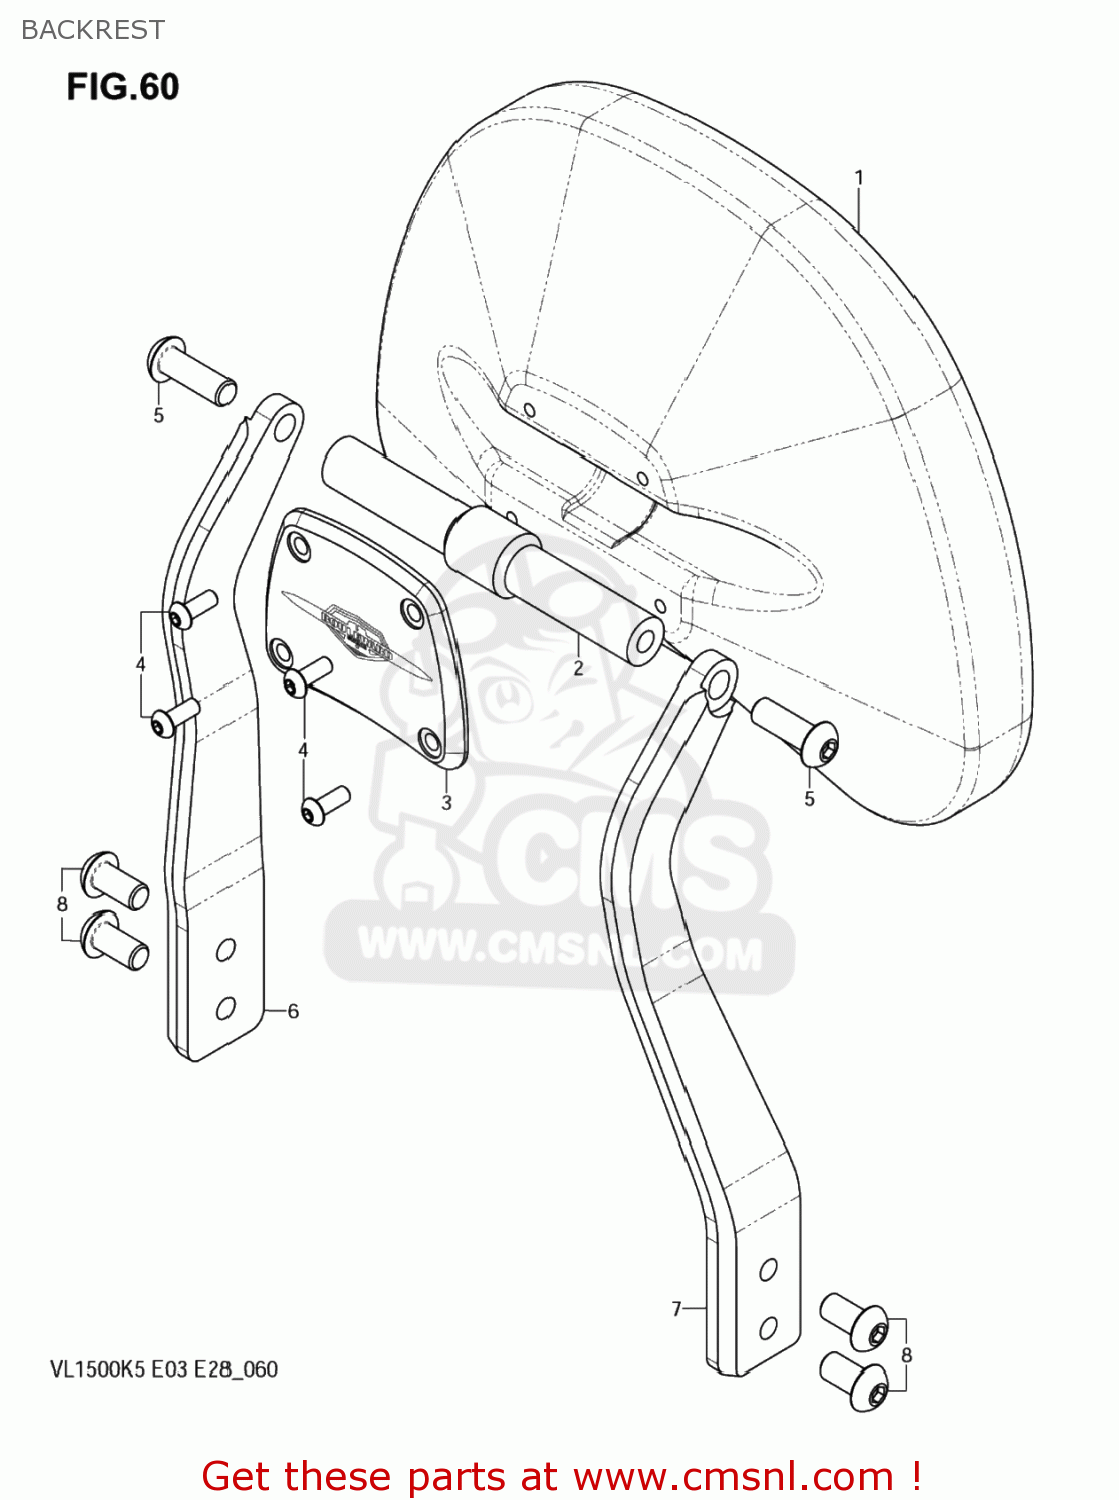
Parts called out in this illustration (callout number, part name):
1	PAD ASSY
1A	.PAD COVER
2	CROSSBAR
3	BACK PLATE
4	SCREW, M6X1.0X20
5	SCREW, M10X1.5X25
6	UPRIGHT, LH
7	UPRIGHT, RH
8	SCREW, M10X1.5X20
9	BACKREST MOUNT PLATE, LH
10	BACKREST MOUNT PLATE, RH
11	SADDLEBAG SUPPORT, LH
12	SADDLEBAG SUPPORT, RH
13	C90T SADDLEBAG
14	C90T SADDLEBAG
15	SADDLEBAG ASSY, LH
16	SADDLEBAG ASSY, RH
17	BOLT, M8X1.25X70
18	TOPHAT WASHER, SADDLEBAG
20	BLVD SADDLBAG E
